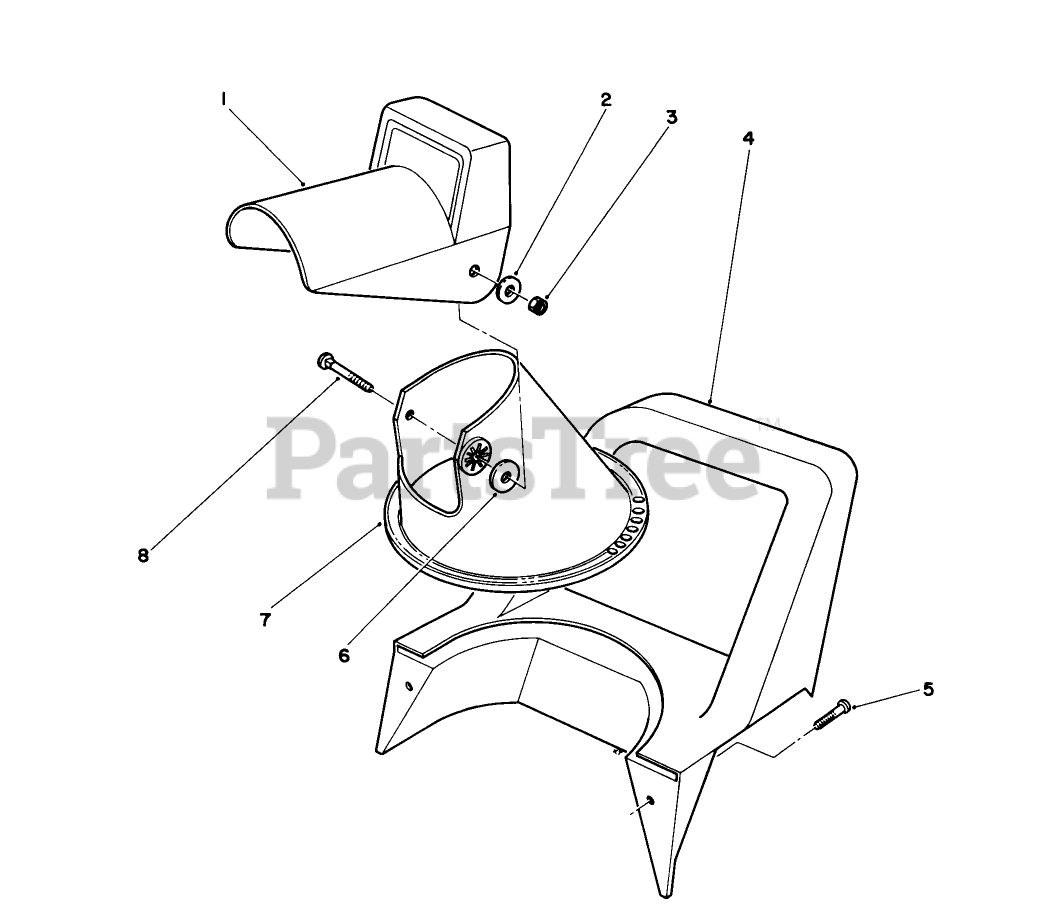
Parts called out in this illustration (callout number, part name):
1	CHUTE-DEFLECTOR
2	WASHER-FLAT
3	NUT-LOCK, NI
4	MIDDLE HANDLE - 1800
6	WASHER-RUBBER
7	LOWER CHUTE, 1800
8	BOLT-CARR
